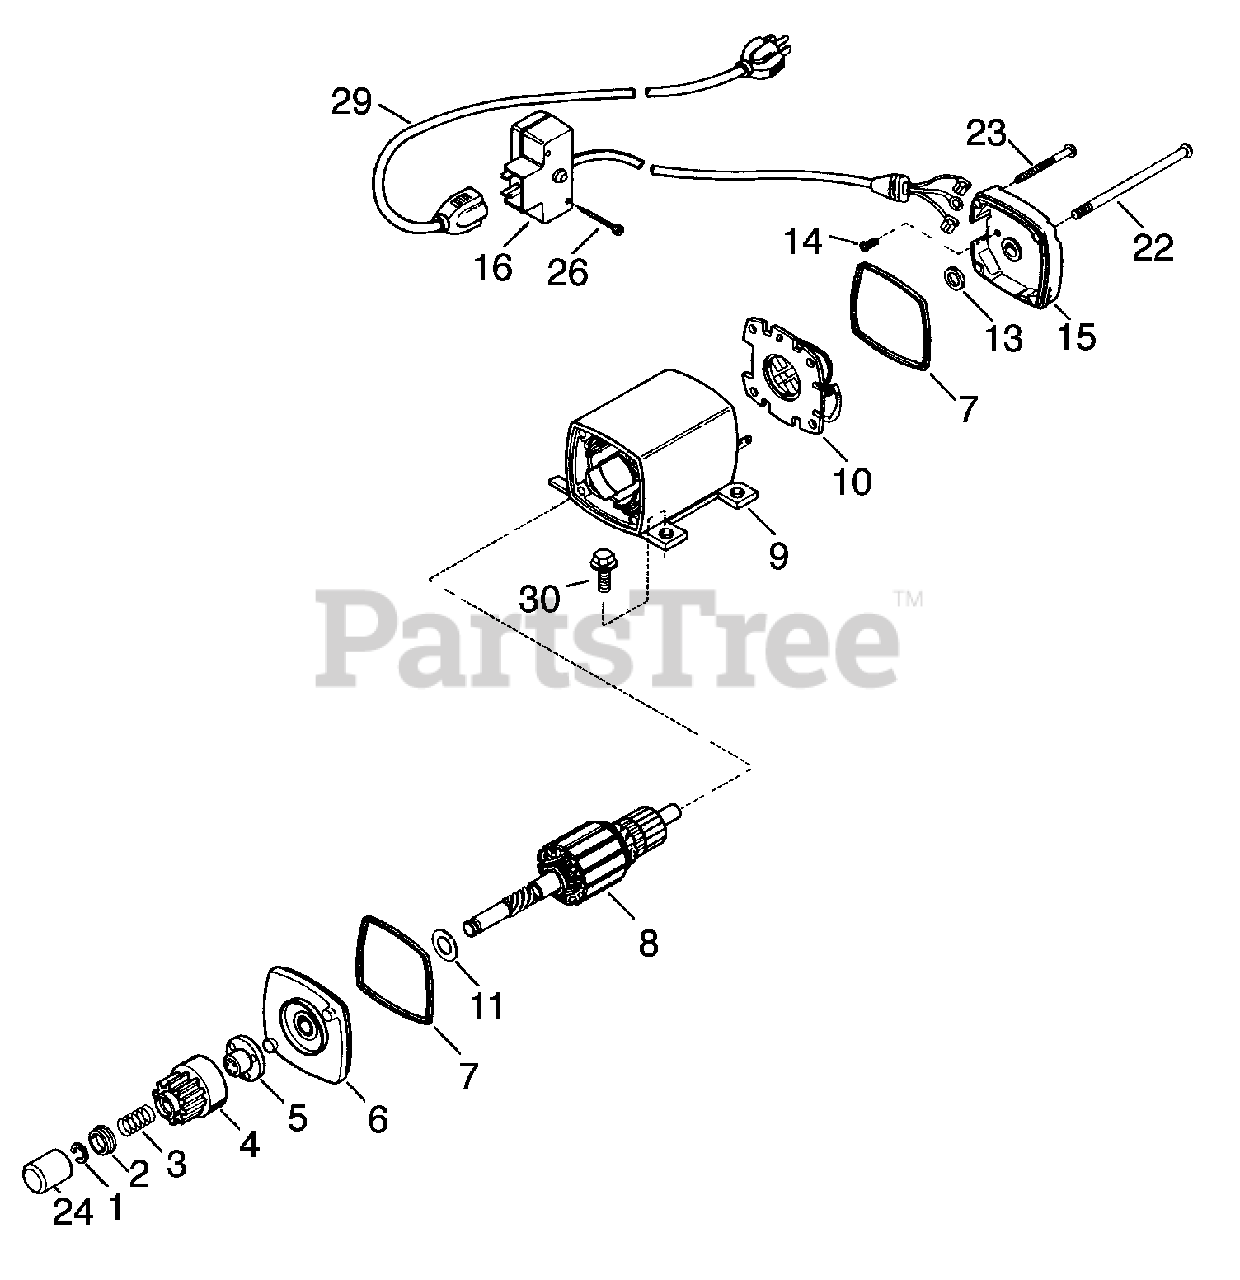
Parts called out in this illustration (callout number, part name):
1	Retainer Ring
2	Spring Retainer
3	Anti-drift Spring
5	Retainer & Nut
6	Drive End Cap Assy
9	Housing Assy
10	Brush Card Assy
11	Trust Washer
13	Thrust Washer
14	Ground Screw
15	Commutator End Cap Assy
16	Switch Box Assy
22	Case Bolt
23	Grounding Screw
24	Dust Cover
26	Screw, 6-32 x 2-1/2"
29	Extension Cord
30	Screw, Torx T-30, 1/4-20 x 1/2"
